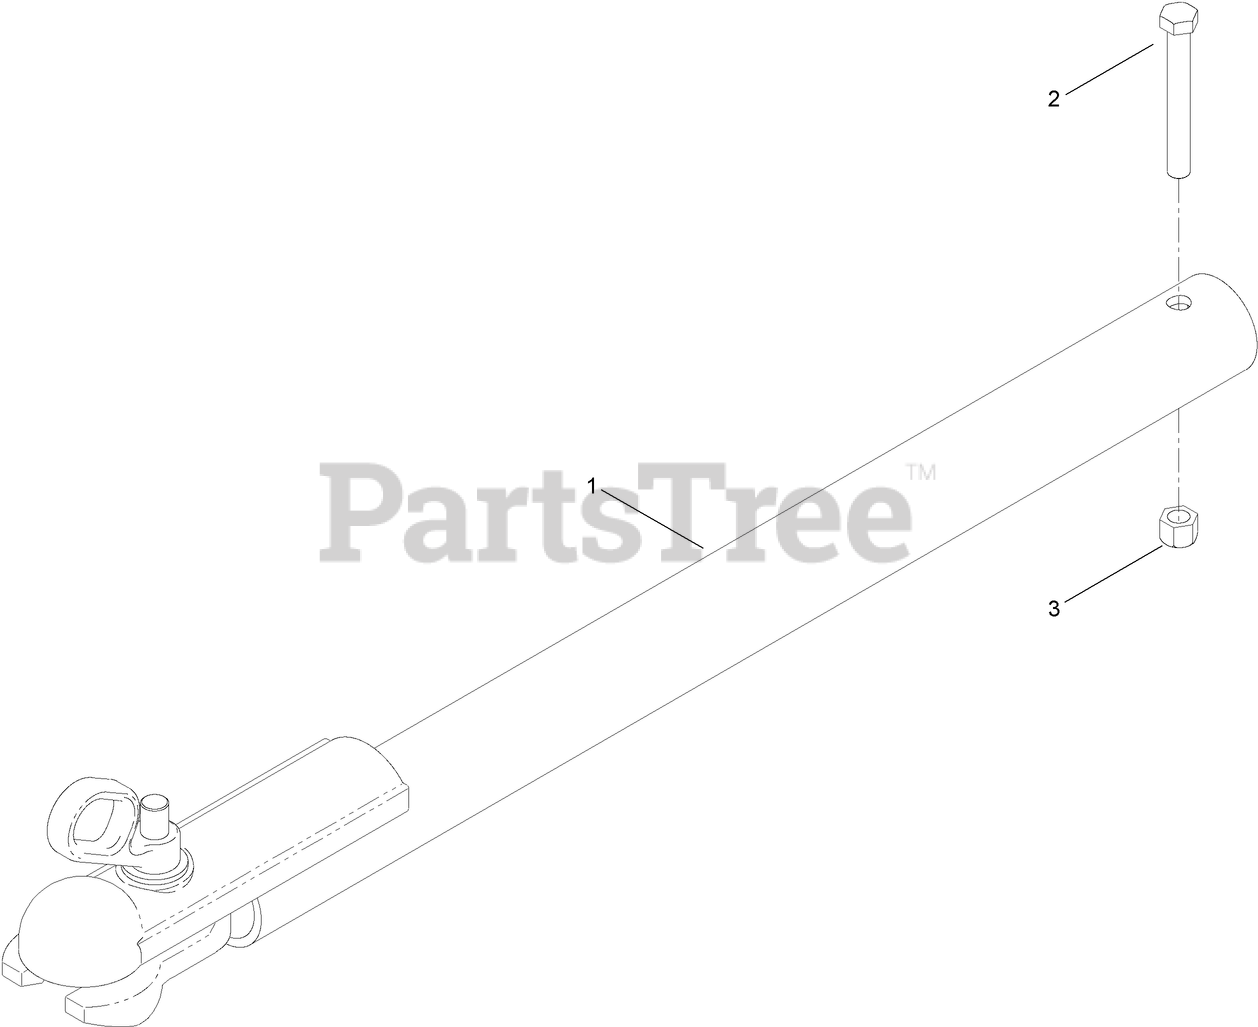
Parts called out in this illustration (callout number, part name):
1	HITCH-BALL, TOW POLE
2	SCREW-HH
3	NUT-LOCK, NI
